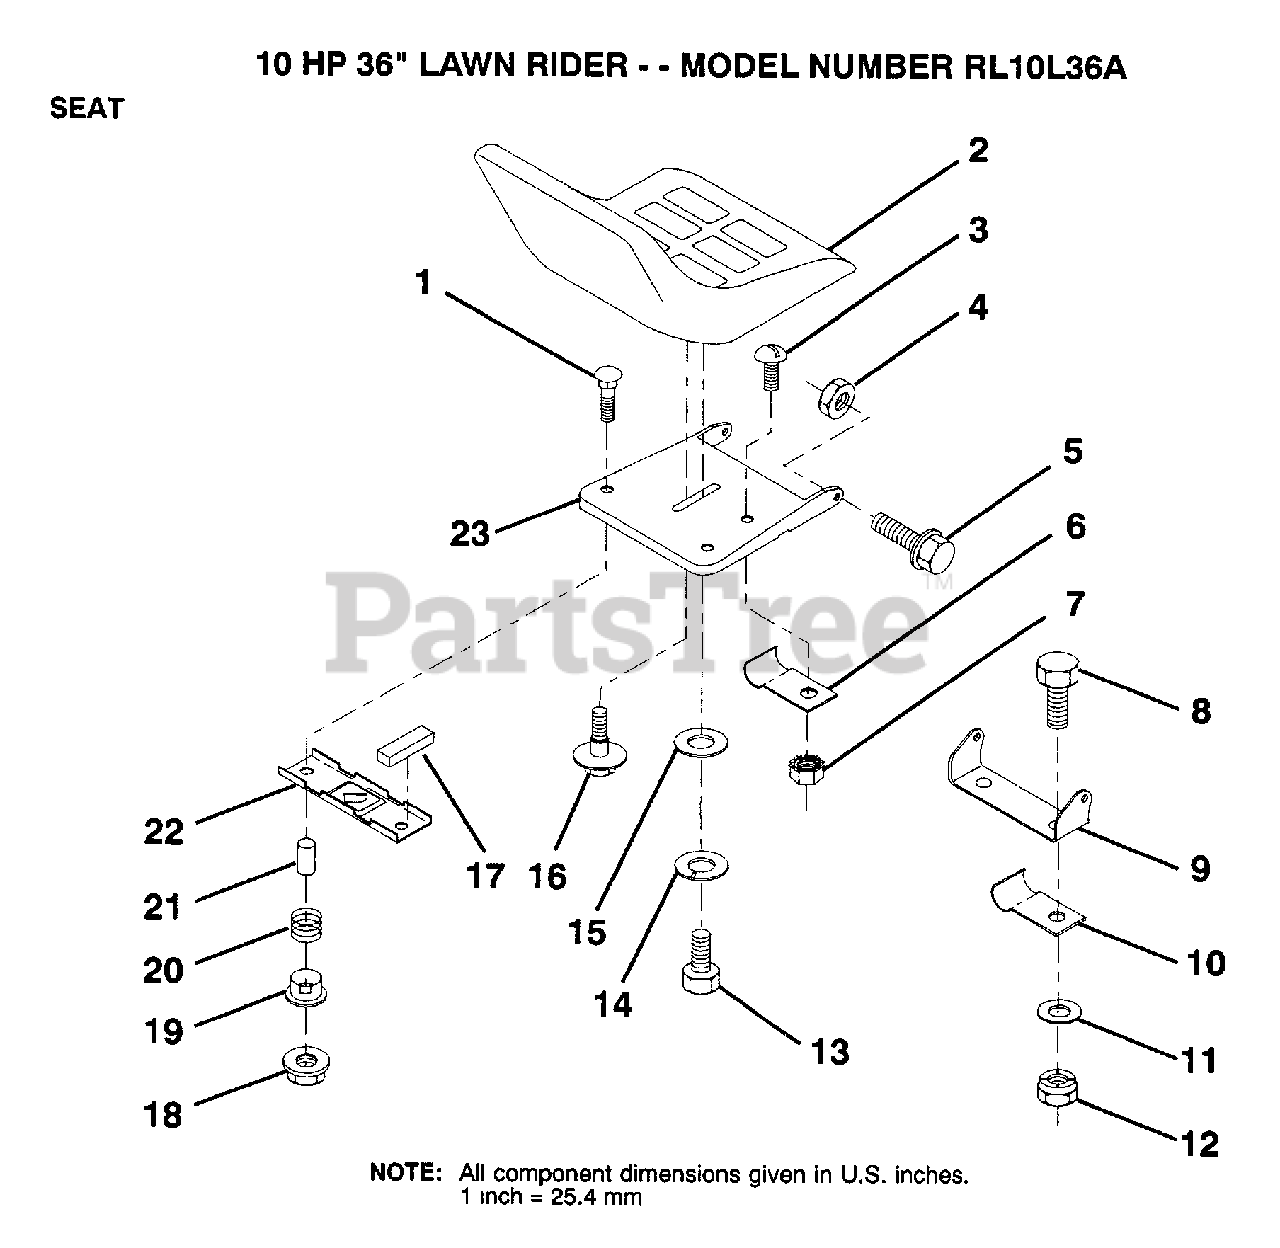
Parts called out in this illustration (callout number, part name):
7	"NUT,KEPS"
10	"CLIP,INSULATOR"
11	WASHER
13	BOLT
14	LOCKWASHER
15	WASHER
16	"BOLT,SHOULDER"
17	STRIP FORM
19	BUSHING
20	SPRING
21	SPACER SPLIT
22	BRKT SWITCH
